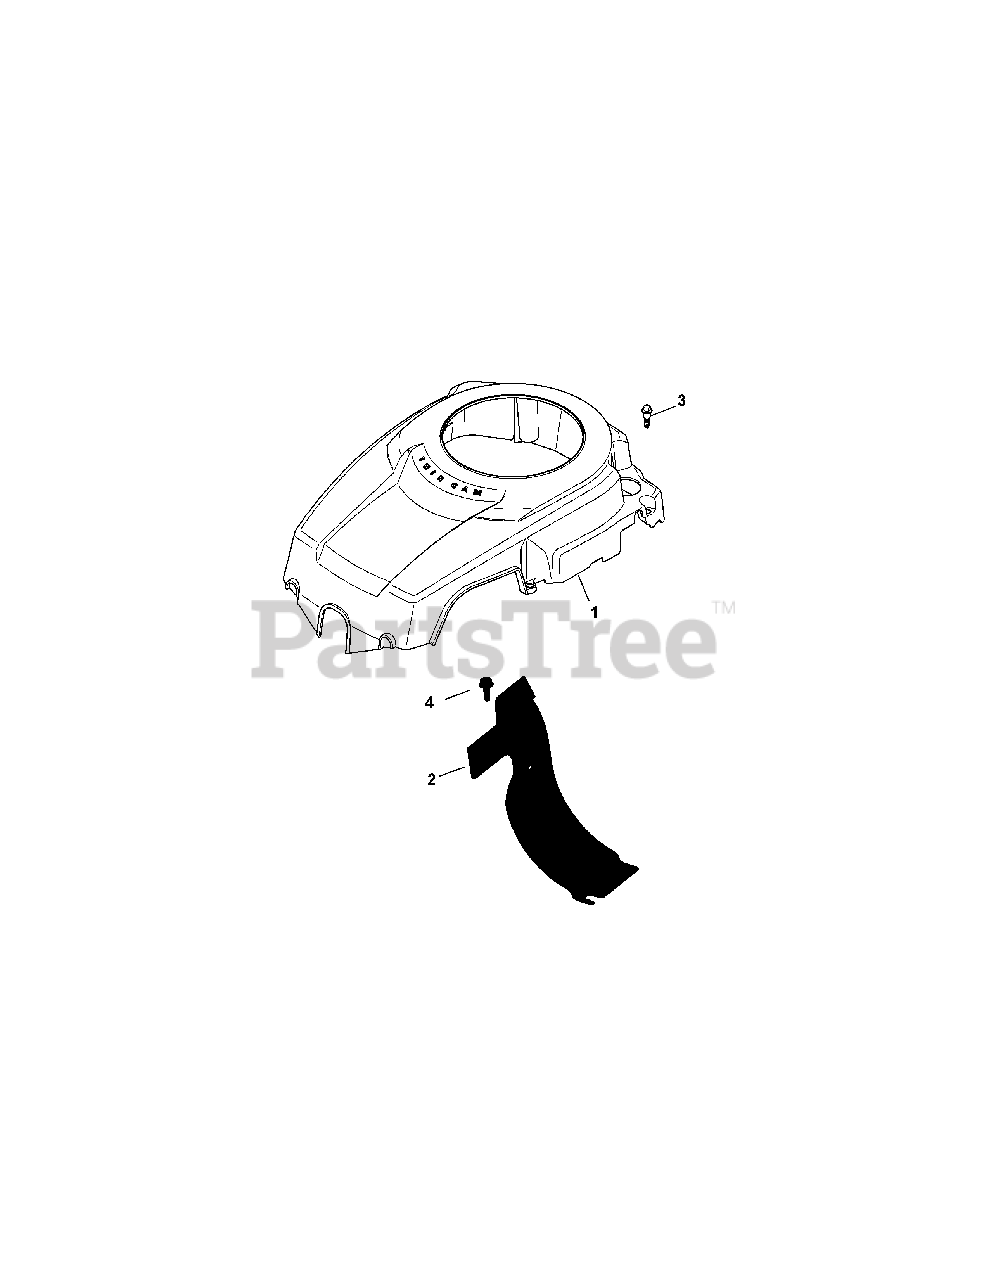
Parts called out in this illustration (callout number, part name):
1	Blower Housing Kit
2	Barrel Baffle
3	Shd. Thd. Frm. Screw, M6 X 1 X 26
4	Flg. Thd. Frm. Screw, M6 X 1.0 X 16
